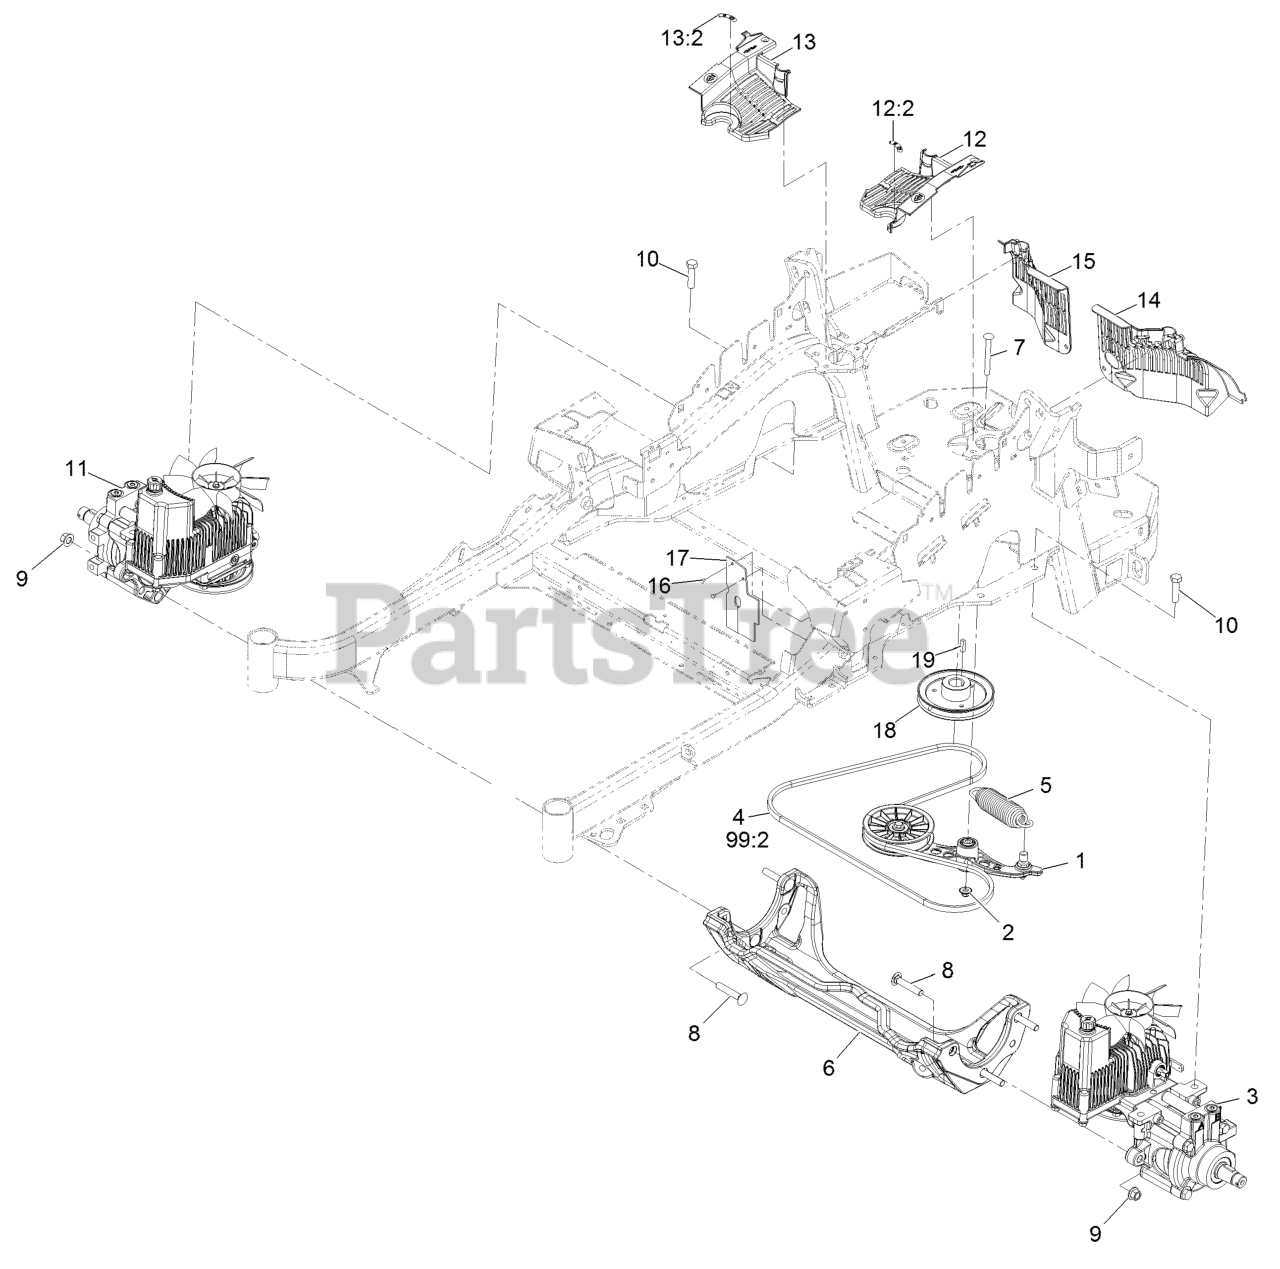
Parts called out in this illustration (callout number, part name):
1	Pump Idler ASM
2	Nut-Nyloc 3/8-16 Flg
3	LH Hydro ASM (12Cc W/ Check)
4	Belt
5	Spring-Extension
6	Cradle-Hydro
7	Bolt-Carriage Shoulder 3/8-16 X 3 1/2
8	Screw-CARR
9	Nut-Lock 1/2-13
10	Screw-HH 1/2-13 X 1 1/4
11	RH Hydro ASM (12Cc W/ Check)
12	LH Hydro Guard ASM
12:2	Decal-Oil, Hydro
13	RH Hydro Guard ASM
13:2	Decal-Oil, Hydro
14	Guard-Hydro, Rear (LH)
15	Guard-Hydro, Rear (RH)
16	Rivet 3/16 X 1/4
17	Deflector-Air Flow
18	Sheave
99	Bottle-Oil, 32Oz Hydraulic
99	Filter-Hydro
99	Bottle,Oil 1 Gallon Hydraulic
99	Kit, Hydro Service
99:1	Bottle-Oil, 32Oz Hydraulic
99:2	Belt
99:3	Filter-Hydro
